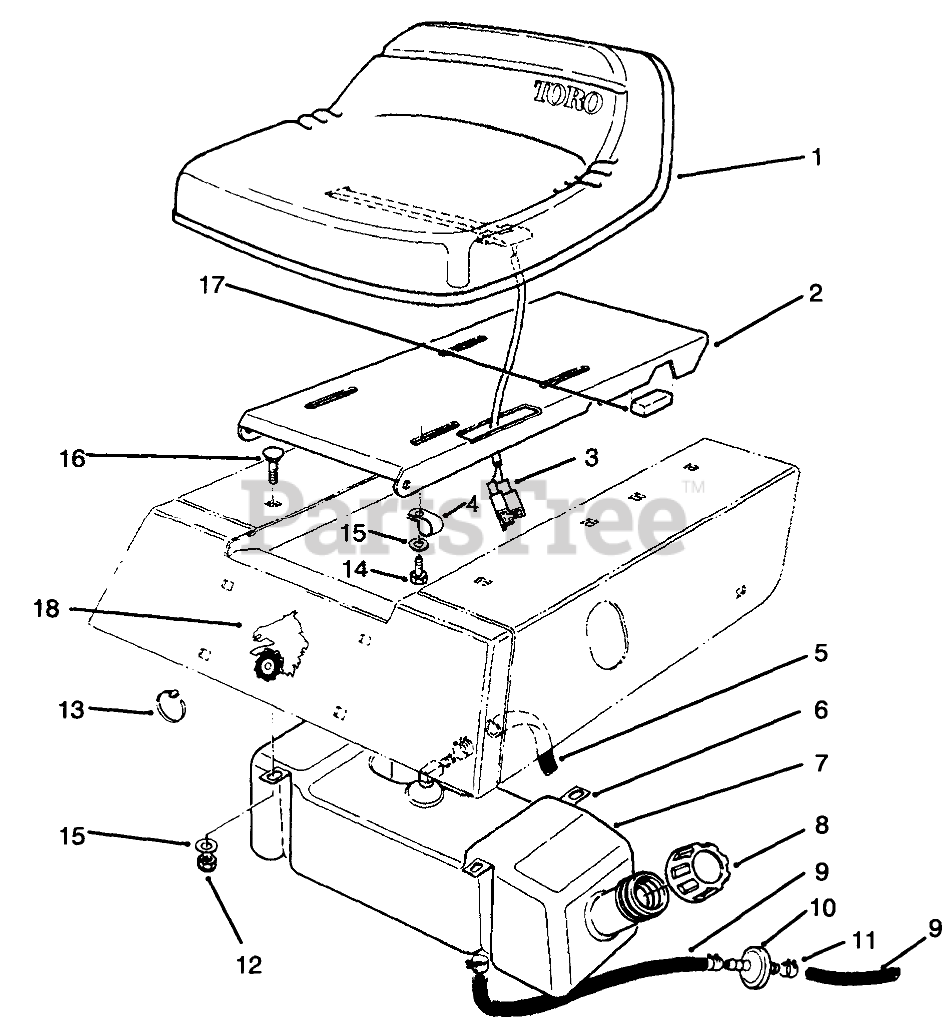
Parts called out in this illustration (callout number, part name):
1	Seat
2	BASE - SEAT
3	SWITCH-SEAT
4	CLIP-FUEL LINE
5	HOSE-FUEL
6	STRAP-GAS TANK
7	TANK-GAS
8	GAS CAP ASM
9	HOSE-FUEL
10	FILTER-FUEL
11	CLAMP-HOSE
12	NUT-LOCK, NI
13	TIE-CABLE
14	SCREW-HH
15	WASHER-PLAIN
16	SCREW-CARR
17	PAD-ISOLATOR
18	DECAL - W.H. INSIGNA
